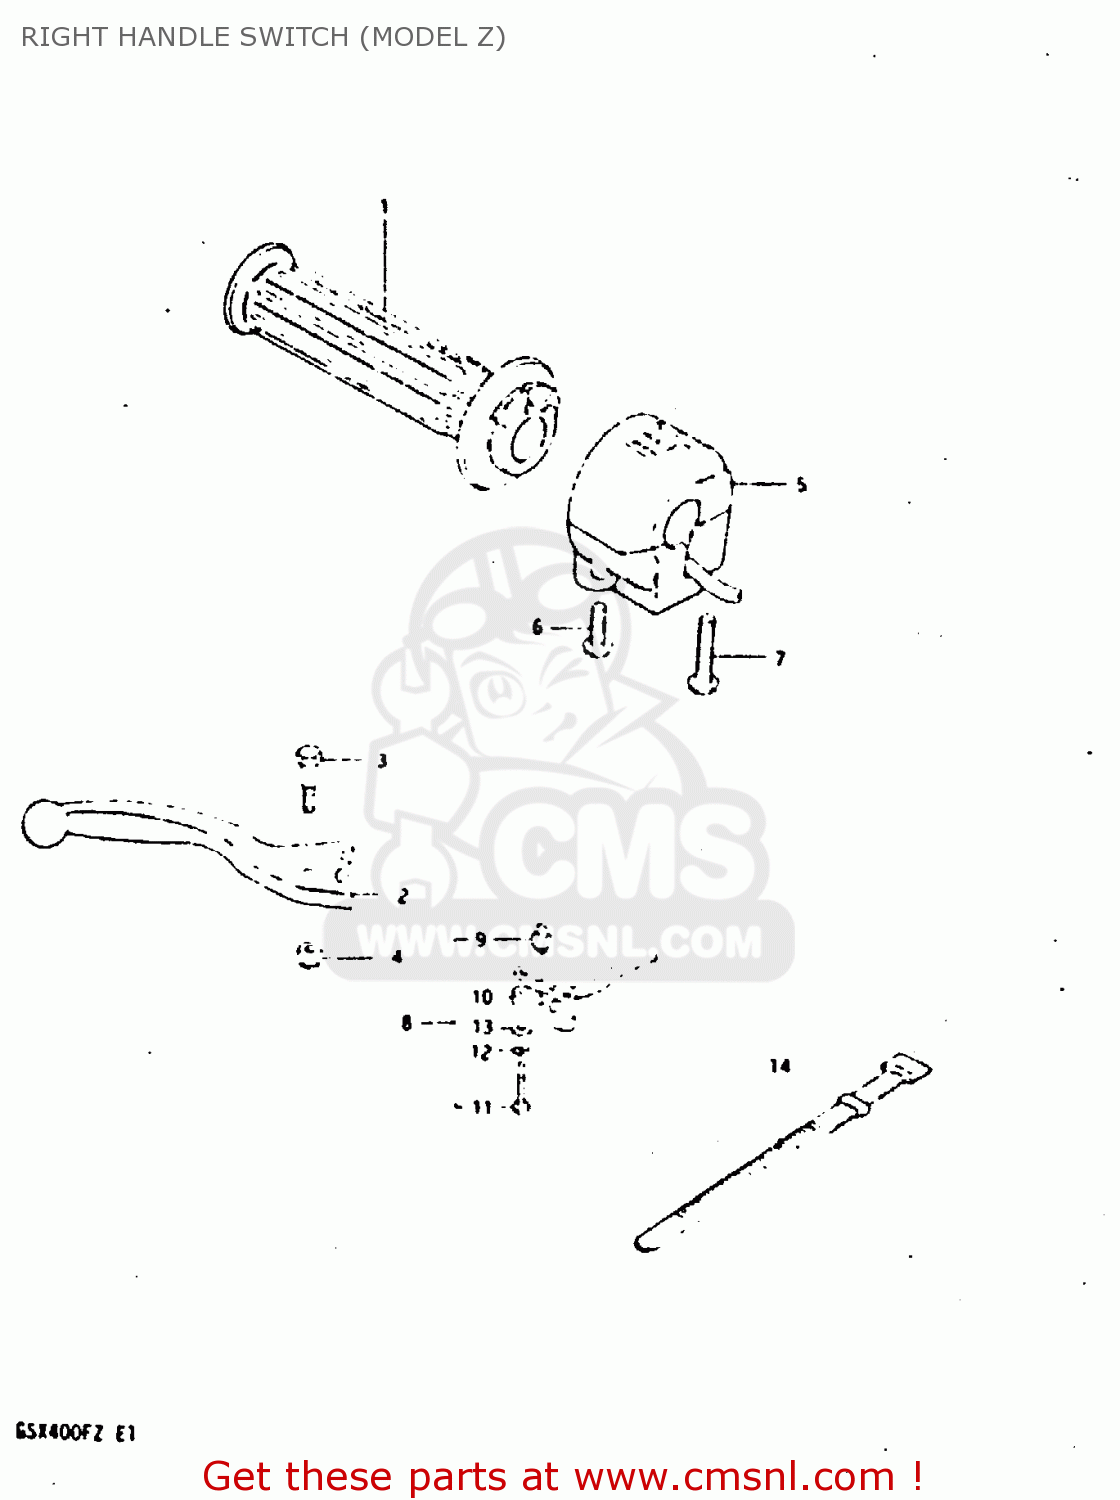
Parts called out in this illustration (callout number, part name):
1	GRIP,THROTTLE
2	LEVER,BRAKE
3	BOLT
4	NUT 6MM
5	SWITCH ASSEMBLY,HANDLE,RIGHT
6	SCREW
7	SCREW
8	SWITCH ASSEMBLY
9	CONTACT,SWITCH
10	COVER,FR BK TERMINAL BASE
11	SCREW
12	LOCK WASHER
13	WASHER
14	CLAMP(L:120)
